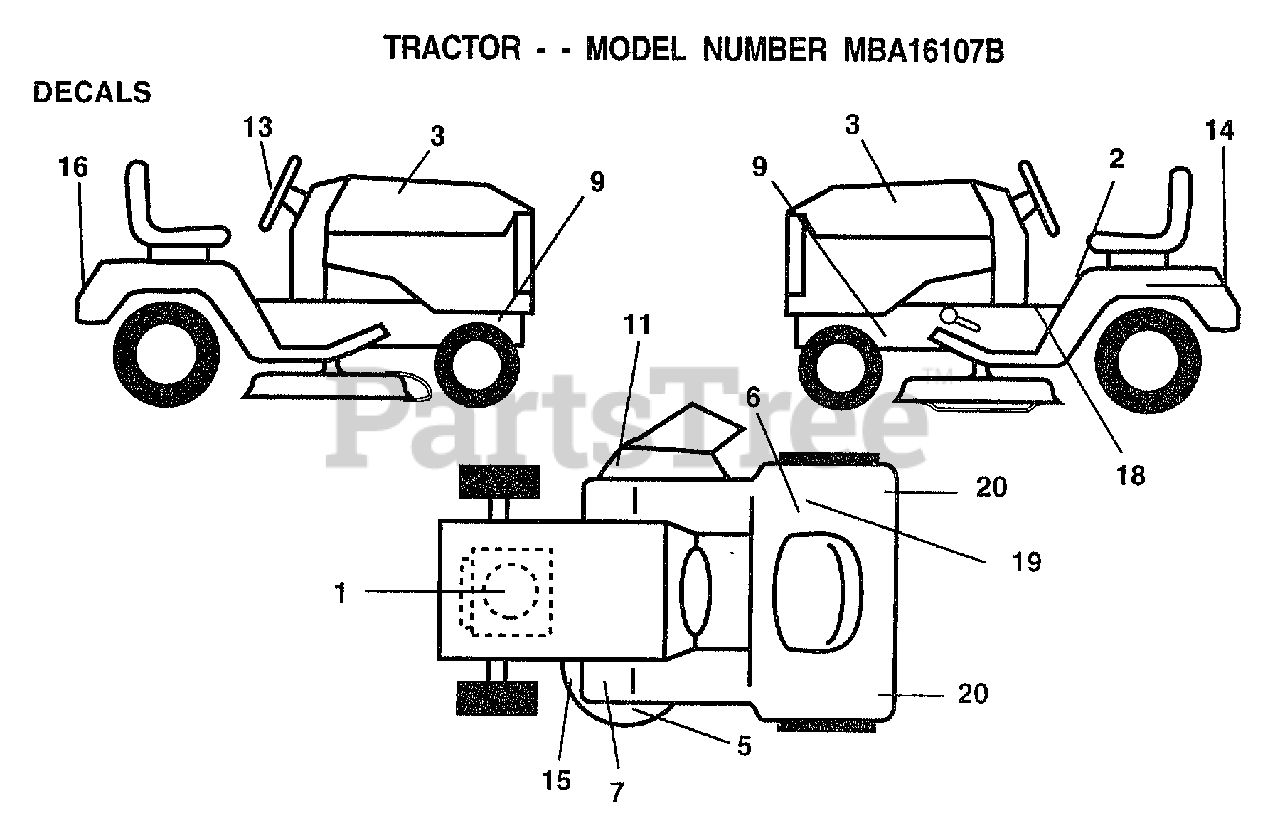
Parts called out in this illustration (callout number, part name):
2	DECAL.READ.O.MANU
3	DECAL HOOD LOGO
5	"DECAL,ENVIRO DECK"
6	DECAL.EURO.ST.CE.
7	DECAL-BRAKE/CLUTC
9	"DECAL CHASSIS,HOT"
11	DECAL.DANGER.CUTF
13	DECAL.WHL.STEERING
14	DECAL.BATRY.3-3908
15	"DECAL-SCHEM,BELT"
16	DECAL FENDER
18	DECAL BRAK PARK
20	REFLECTOR-TAIL YT
